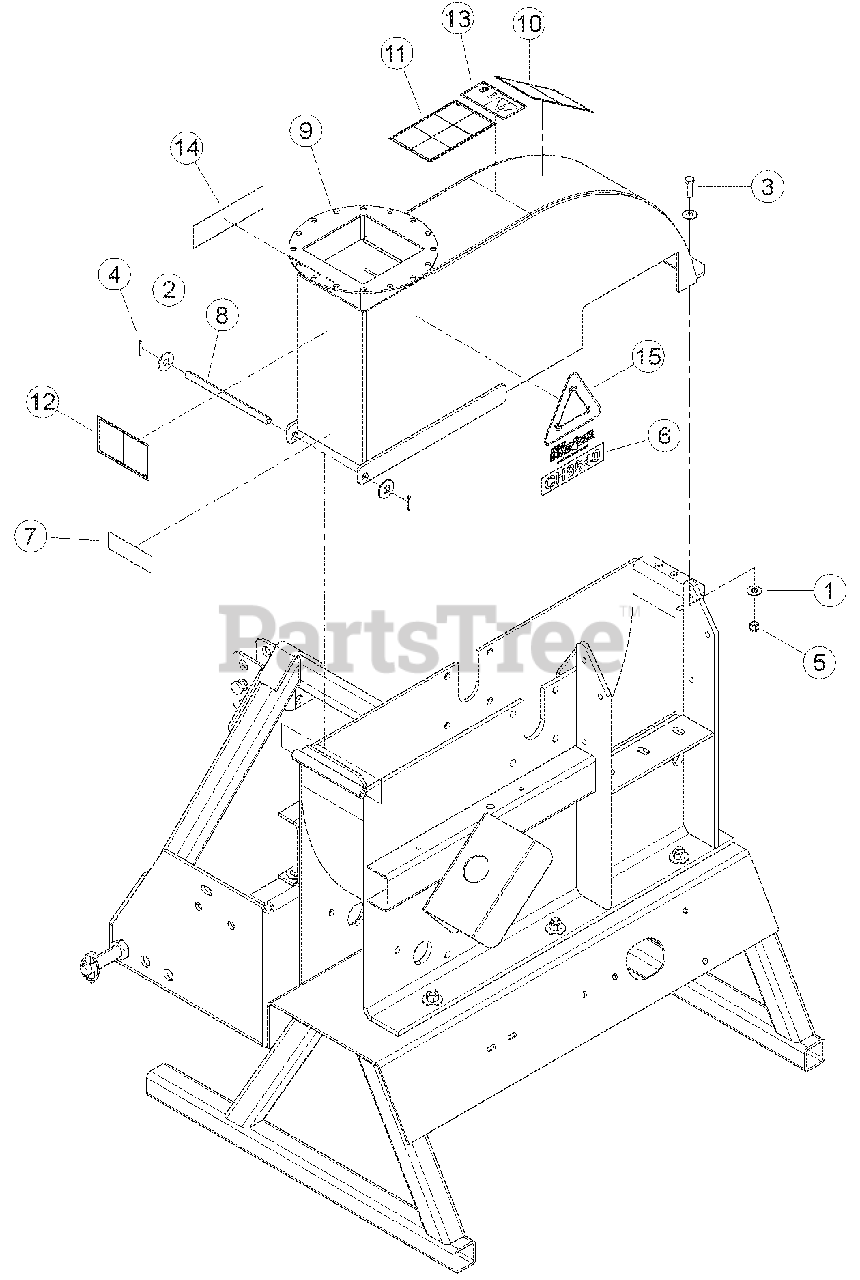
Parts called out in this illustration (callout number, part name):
1	WASHER, 3/8 FLAT ZP
2	WASHER, 1/2 FLAT ZP
3	BOLT, 3/8 X 1-1/4 HEX HD GR5 ZP
4	PIN, 1/8 X 1.00 ZP COTTER
5	NUT, 3/8 NE NYLOCK ZP
6	DECAL, MODEL CH8540
7	DECAL, ATLANTIC BRIDGE LTD INFO (CE COMPLIANT MODELS)
8	SHAFT CHIPPER TOP PIVOT
9	ASSEMBLY, CHIPPER TOP HOUSING, SERVICE PART
10	DECAL, KNIFE ACCESS ISO
11	DECAL, OPERATING INSTRUCTIONS ISO
12	DECAL, DISCHARGE ISO
13	DECAL, MAINTENANCE ISO
14	DECAL, ECHO BEARCAT 6.82 X 1.90
15	DECAL, CHIP IT
